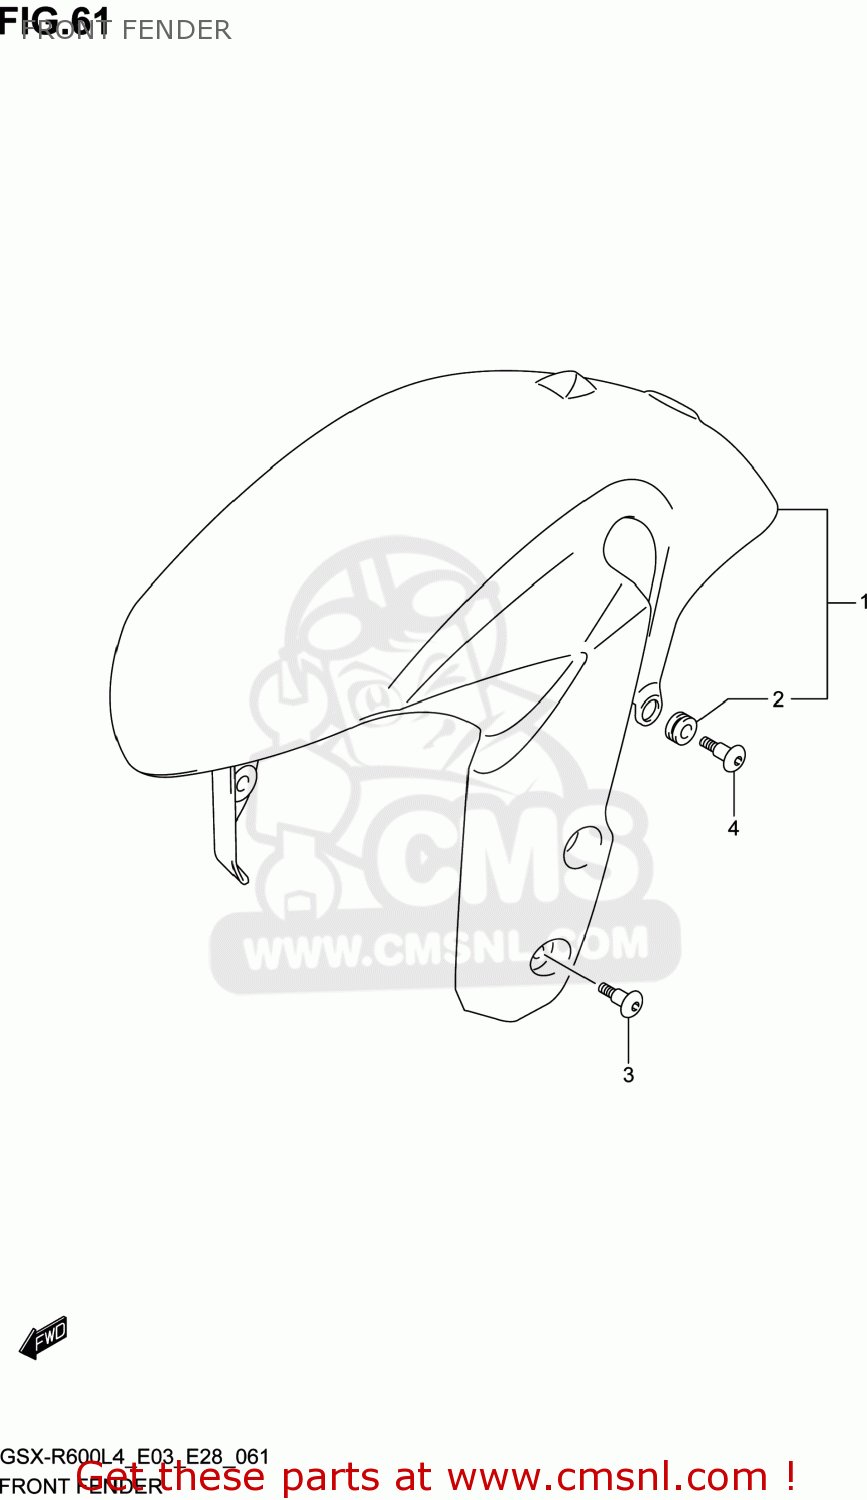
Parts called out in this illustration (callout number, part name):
1	FENDER ASSY,FR(BLACK)
2	CUSHION
3	SCREW(6X16)
4	SCREW(6X16)
